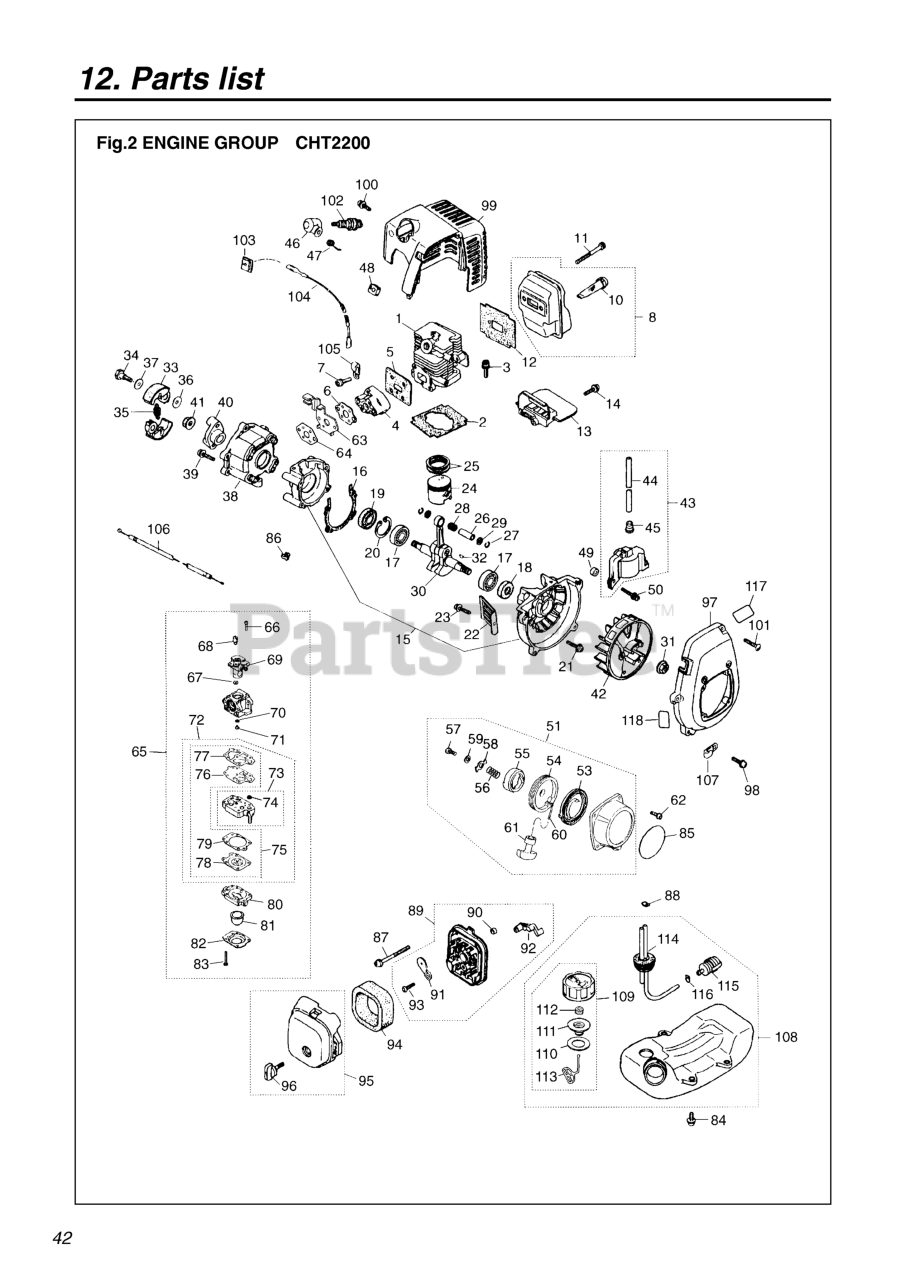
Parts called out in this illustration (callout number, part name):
1	CYLINDER
2	GASKET, BASE (RPLS -12212)
3	BOLT, M5 X 22
4	INSULATOR (REPLACES -13162)
5	GASKET (RPLS -13120)
6	GASKET (REPLACES -13130)
7	SCREW, M5X20 (RPLS.1400-75510)
8	MUFFLER ASSEMBLY
10	ARRESTER (RPLS 5850-15140)
11	BOLT, M5 x 50
12	GASKET, MUFFLER
14	SCREW, M4 X 16
15	CRANKCASE COMP.
16	GASKET (RPLS -21140)
17	BEARING
18	SEAL, OIL (RPLS 1100-21210)
19	SEAL, OIL (RPLS 1140-21220)
20	RING, SNAP, M28 x 1.2
21	BOLT, M5 X 30
23	SCREW,M5 X 14 (RPLS 1400-15510
24	PISTON (REPLACES 1140-41110)
25	RING, PISTON (RPLS 1850-41210)
26	PIN, PISTON 5x8x26
27	RING, SNAP (RPLS 1101-41320)
28	BEARING (RPLS 1140-41330)
29	WASHER
30	CRANKSHAFT (RPLS -42000)
32	KEY
33	SHOE (RPLS 1100-51114)
34	BOLT
35	SPRING
36	WASHER, FLAT (USE 182303)
38	CASE, CLUTCH
39	SCREW
40	PLATE, CLUTCH
43	COIL
45	CAP
46	CAP
47	SPRING
48	GROMMET
49	SPACER (RPLS -71260)
50	BOLT
51	RECOIL-ASSY (RPLS -75101)
53	SPRING
54	REEL (RPLS-75130 & 1861-75130)
55	RACHET (RPLS.-75140)
56	SPRING (REPLACES -75150)
58	RETAINER
59	WASHER
60	ROPE
61	KNOB (REPLACES-75180)
62	SCREW, M4 x 12
63	BRACKET
64	GASKET (REPLACES -13130)
65	CARBURETOR
67	RING
68	SWIVEL
69	VALVE
70	RING, O
73	BODY, PUMP
74	SCREEN
76	DIAPHRAGM, PUMP
77	GASKET, PUMP
78	DIAPHRAGM
79	GASKET, DIAPHRAGM
80	BODY, PURGE
81	PUMP, PRIMING
82	COVER, PUMP
83	SCREW
84	SCREW
85	LABEL, RECOIL
86	CAP, CABLE END
87	SCREW, M5 x 60
88	CLIP
89	BODY-A (RPLS -82101)
90	SLEEVE
91	PLATE, CHOKE (RPLS-82130)
92	LEVER, CHOKE
93	SCREW (REPLACES 50030272)
94	ELEMENT
95	COVER ASSY (RPLS -82202)
96	KNOB (RPLS -82220)
97	COVER, FAN
98	SCREW, M5X20 (RPLS.1400-75510)
99	ENGINE COVER (RPLS-32100)
100	SCREW, M5 x 12
101	SCREW, HOUSING
102	PLUG, SPARK (RPLS 5602-73110)
104	CORD
105	CLAMP (RPLS 1140-72231)
106	CABLE
107	CLAMP (RPLS 1140-72231)
108	TANK ASSY (RPLS-85001)
109	CAP ASSY (RPLS. 5601-85201)
110	PACKING
111	HOLDER - A (RPLS 5601-85230)
112	FILTER
113	STOPPER
114	PIPE COMPLETE
115	FILTER (RPLS 1850-85300)
116	CLIP (REPLACES 2841-31280)
117	LABEL, CAUTION
